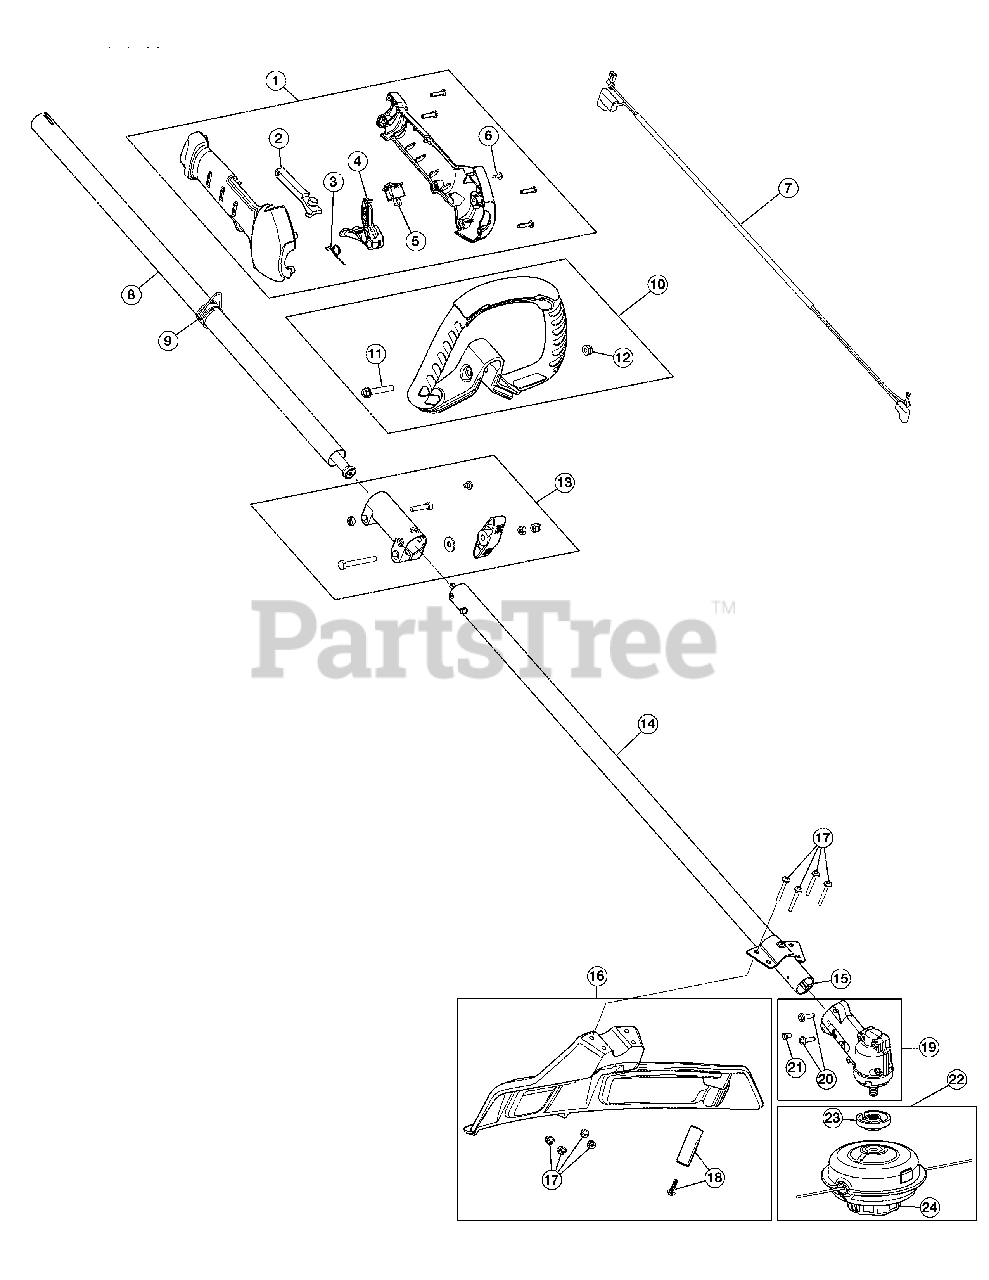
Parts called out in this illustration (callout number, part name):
1	Throttle Housing Assembly (Incl. 2 - 6)
2	Throttle Lockout
3	Throttle Trigger Spring
4	Throttle Trigger
6	Grip Anti-Rotation Screw
7	Throttle Cable
8	Upper Drive Shaft Housing
9	Shoulder Strap Clip
10	D-Handle Assembly (Incl. 11 and 12)
13	Split Boom Coupler
14	Lower Drive Shaft Housing Assembly (Incl. 15)
15	Lower Flexible Drive Shaft
16	Shield Assembly (Incl. 17)
17	Shield Mounting Screws and Nuts
18	Blade Assembly
19	Gearbox Assembly (Incl. 20 - 24)
20	Gearbox Mounting Hardware
21	Anti-Rotation Screw
22	Cutting Head Assembly
23	Cutting Head Driver
